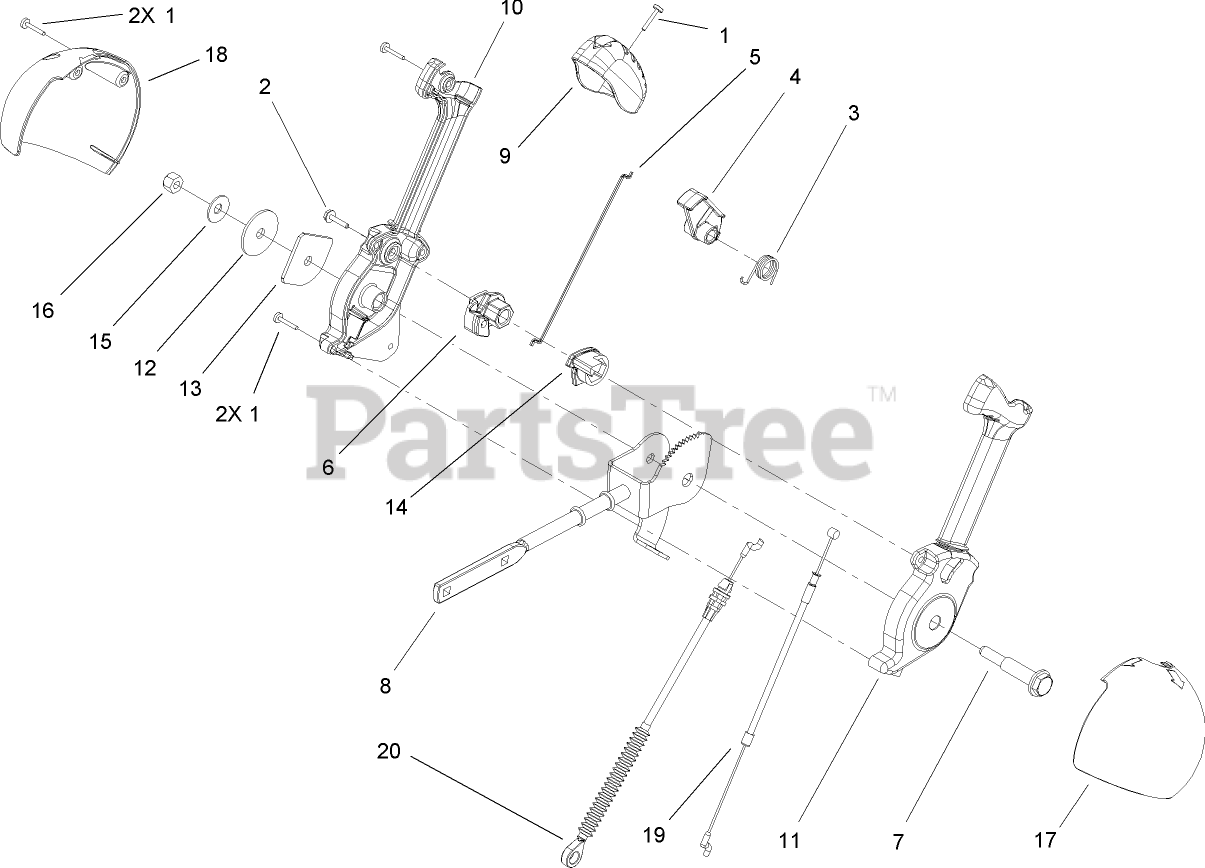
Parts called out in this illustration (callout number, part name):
1	SCREW-PPH
2	SCREW-HWH
3	SPRING-TORSION
4	TRIGGER-LATCH
5	LINK-LATCH
6	LEVER-CABLE, DEFLECTOR
7	SCREW-SHOULDER
9	CAP-LEVER
10	LEVER-CONTROL, CHUTE (RH)
11	LEVER-CONTROL, CHUTE (LH)
12	WASHER-NYLON
14	PAWL-LATCH
15	WASHER-BELLEVILLE
16	NUT-LOCK, NI
17	COVER-LEVER, CHUTE (LH)
18	COVER-LEVER, CHUTE (RH)
19	CABLE-RELEASE, CHUTE
20	CABLE-CONTROL, DEFLECTOR
